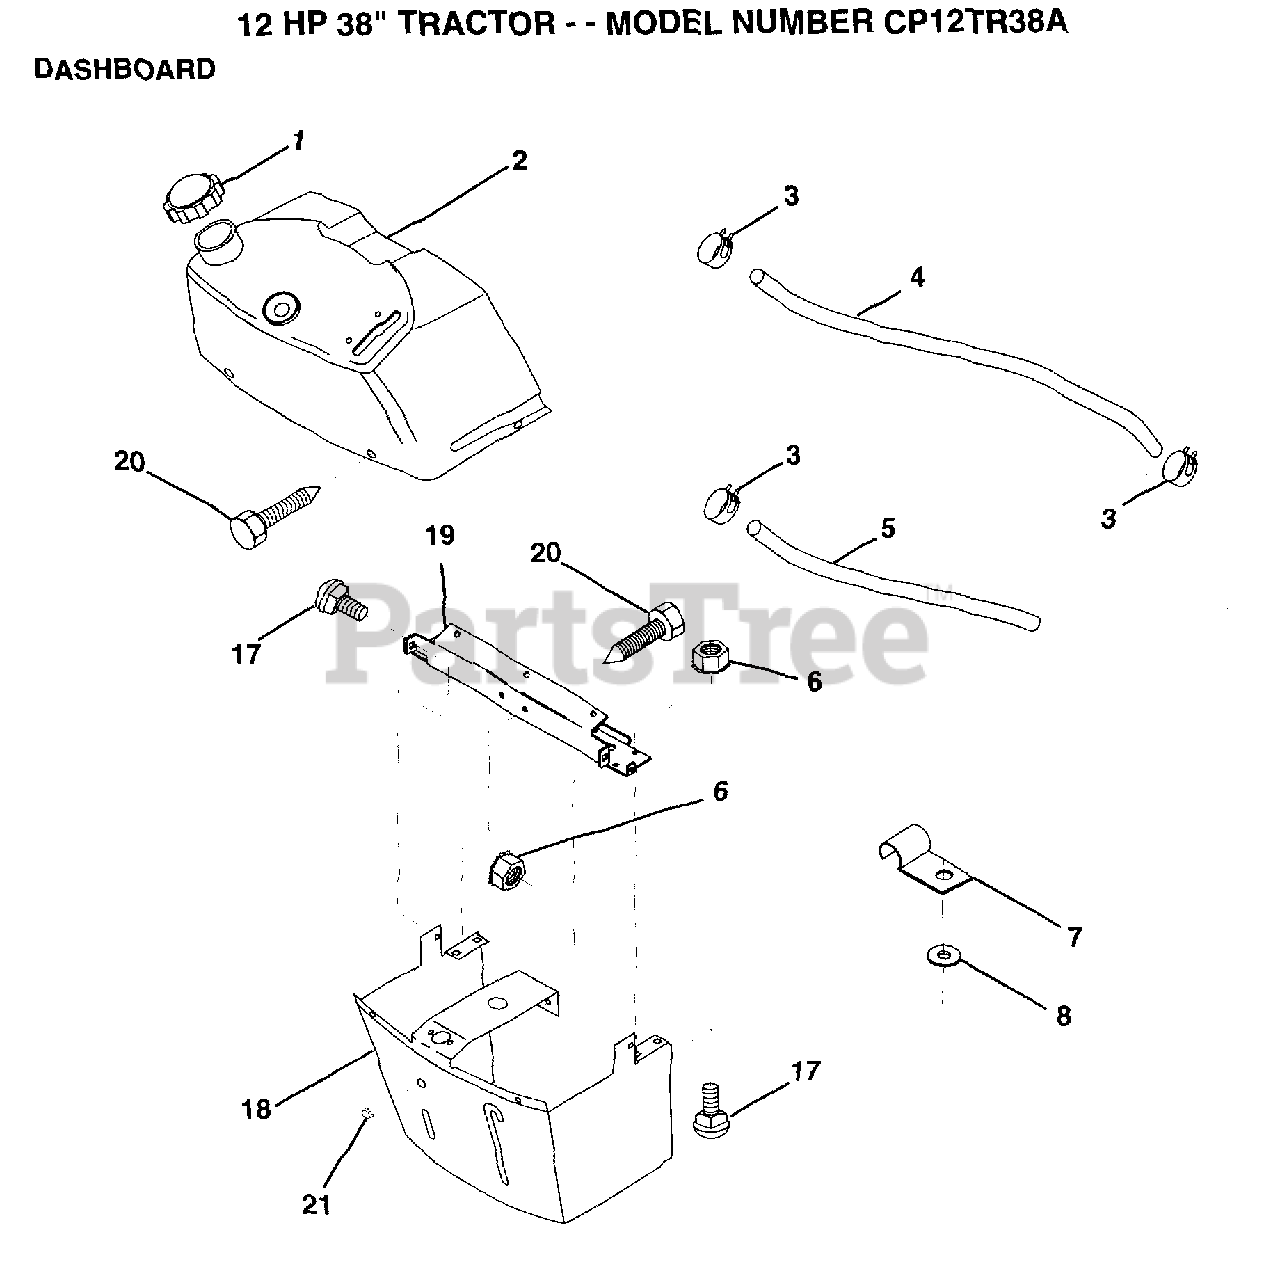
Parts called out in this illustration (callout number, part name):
1	CAP BLK FUEL LR
2	TANK.ASM.DASH.LR
3	HOSE CLAMP
5	FUEL LINE T
6	NUT
7	CLIP T
8	WASHER PM
17	BOLT
18	SUPT ASM DASH
19	CROSS BRACE
20	SCREW.1/4-20X1/2
21	PLUG DOME
